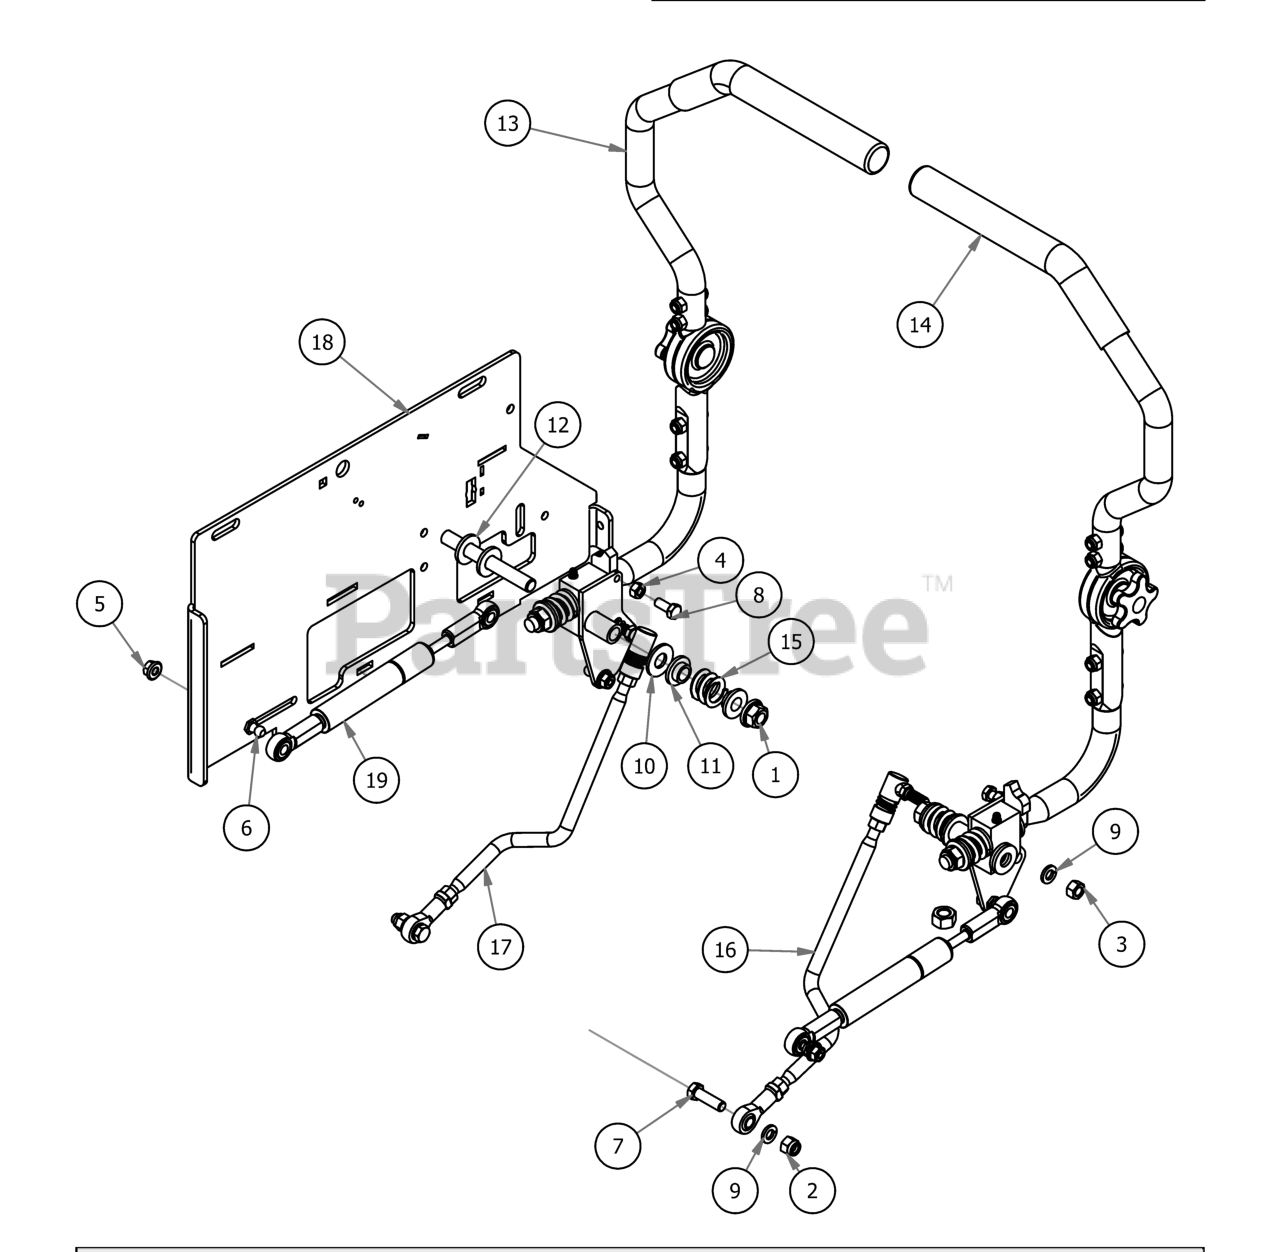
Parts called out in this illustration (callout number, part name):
1	1/2-13 Mechanical Lock Nut
2	3/8 Nylock Nut
3	3/8" Fine Threaded Jam Nut
5	5/16" Flange Nut
6	10mm Damper Ball Stud-Steering
7	3/8" x 1 1/4" Hex Bolt
8	5/16" x 3/4" Hex Bolt
9	3/8" Lock Washer
10	1/2" Washer (Grade 8)
11	.515 ID Nylon Shoulder Washer
12	.505 Nylon Spacer
13	2018 Steering Arm Assembly-Left
14	2018 Steering Arm Assembly-Right
15	Drive Lever Spring
16	Push Rod-Right
17	Push Rod-Left
18	2018 Maverick Frame
19	Steering Damper
